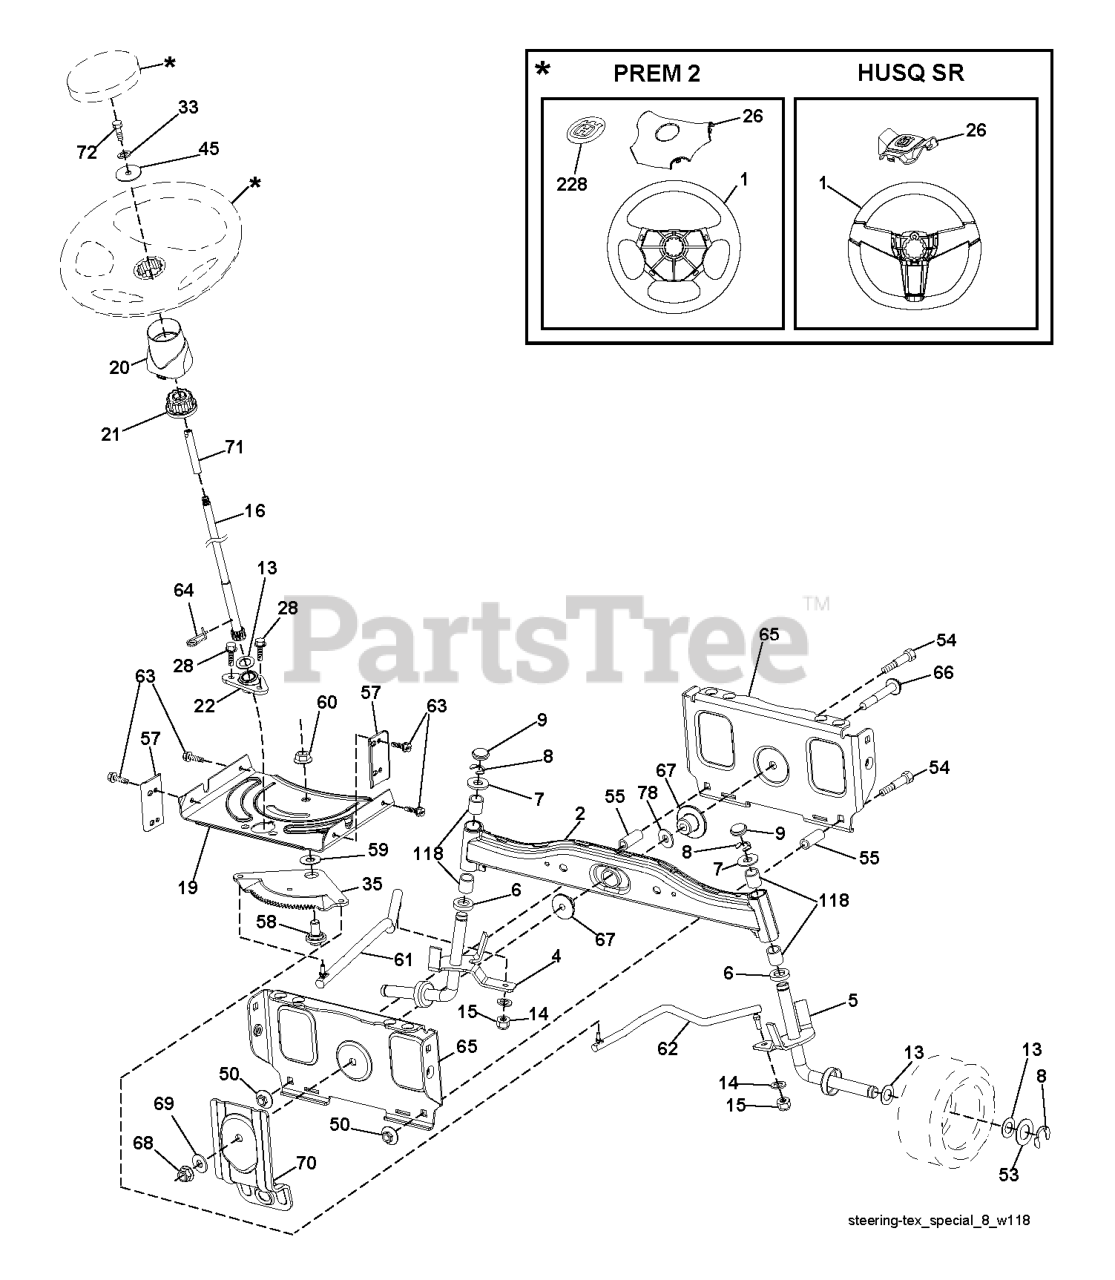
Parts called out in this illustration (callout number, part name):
1	RP WHEEL.STEER.HUSQ.PREM.OVMLD
2	AXLE ASSY FRONT
4	SPINDLE.WELDED.LH.15"TEX
5	SPINDLE.WELDED.RH.15"T
6	THRUST WASHER
9	CAP.SPINDLE.BLACK
14	WASHER, LOCK 3/8
15	NUT CROWNLOCK 3/8-24
16	SHAFT STEERING
19	PLATE.STEER.DDL.NLT/NG
20	BOOT, STEERING
21	ADAPTER, WHEEL STNG..
22	BUSHING.ASM.STEERING.A
26	RP INSERT.CAP.WHL.STRG.HUSQ.
28	SCREW, 3/8-16X3/4
33	WASHER.LOCK.HVY.HLCL.SPR.5/16
35	GEAR.SECTOR.PLATE.DDL.
45	WASHER.11/32
50	NUT LOCK FLG 3/8-16 UNC
53	WASHER.HARDENED
55	SPACER.BRACE.AXLE
57	BRACKET.UPSTOP.TEX
58	BOLT.SHOULDER.SECTOR.P
59	WASHER.THURST.SECTOR.S
60	NUT FLANGE LOCK 5/8-11
61	DRAGLINK.LH.BALLSTUD.D
62	DRAGLINK.RH.BALLSTUD.D
63	SCREW
64	RETAINER.CLIP.SPRING.S
65	BRACE.AXLE.FRONT.NLT/N
66	BOLT HEX FGHD 7/16-14 X 3 SERR
67	BUSHING.PM.FRONT AXLE
68	NUT.LOCK.FLANGE.7/16
69	WASHER.1.5X.505X.118
70	BRKT.DECK.SUSPENSION.F
71	SHAFT EXTENSION STEERING
72	BOLT YT
78	THRUST WASHER
118	BUSHING, AXLE CAST
